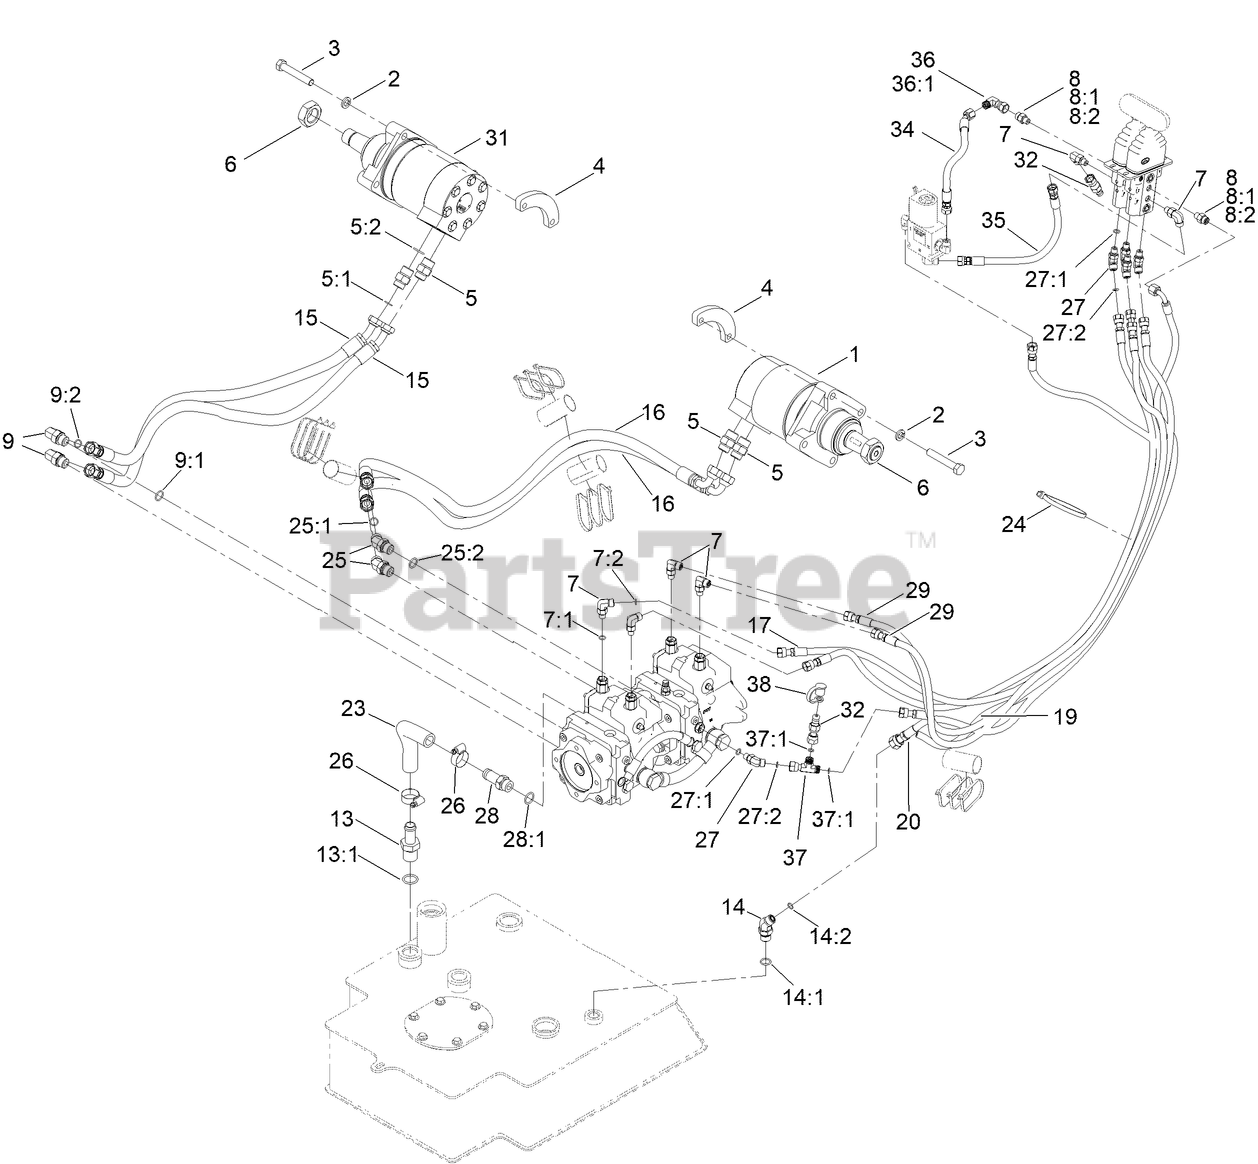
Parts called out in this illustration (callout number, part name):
1	MOTOR-HYD
2	WASHER-LOCK
3	SCREW-HH, TAP
4	PLATE-MOUNTING, WHEELMOTOR
5	FITTING-STRAIGHT
5:1	O-RING
5:2	O-RING
6	NUT-HEX
7	FITTING-ELBOW, 90 DEG
7:1	O-RING
7:2	O-RING
8	FITTING-STRAIGHT
8:1	O-RING
8:2	O-RING
9	FITTING-ELBOW, 90 DEG
9:1	O-RING
9:2	O-RING
13	FITTING
13:1	O-RING
14	FITTING-HYD, 45 DEG
14:1	O-RING
14:2	O-RING
15	HOSE-HYD
16	HOSE-HYD
17	HYD HOSE ASM
19	HYD HOSE ASM
20	HYD HOSE ASM
23	HOSE-RETURN
24	TIE-CABLE
25	FITTING-HYD, 45 DEG
25:1	O-RING
25:2	O-RING
26	CLAMP-HOSE
27	FITTING-HYD, 45 DEG
27:1	O-RING
27:2	O-RING
28	FITTING-STR
28:1	O-RING
29	HYD HOSE ASM
31	MOTOR-HYD
32	NIPPLE-TEST
34	HOSE ASM
35	HOSE ASM
36	FITTING-ADAPTOR
36:1	O-RING
37	FITTING-HYD
37:1	O-RING
38	CAP-DUST
